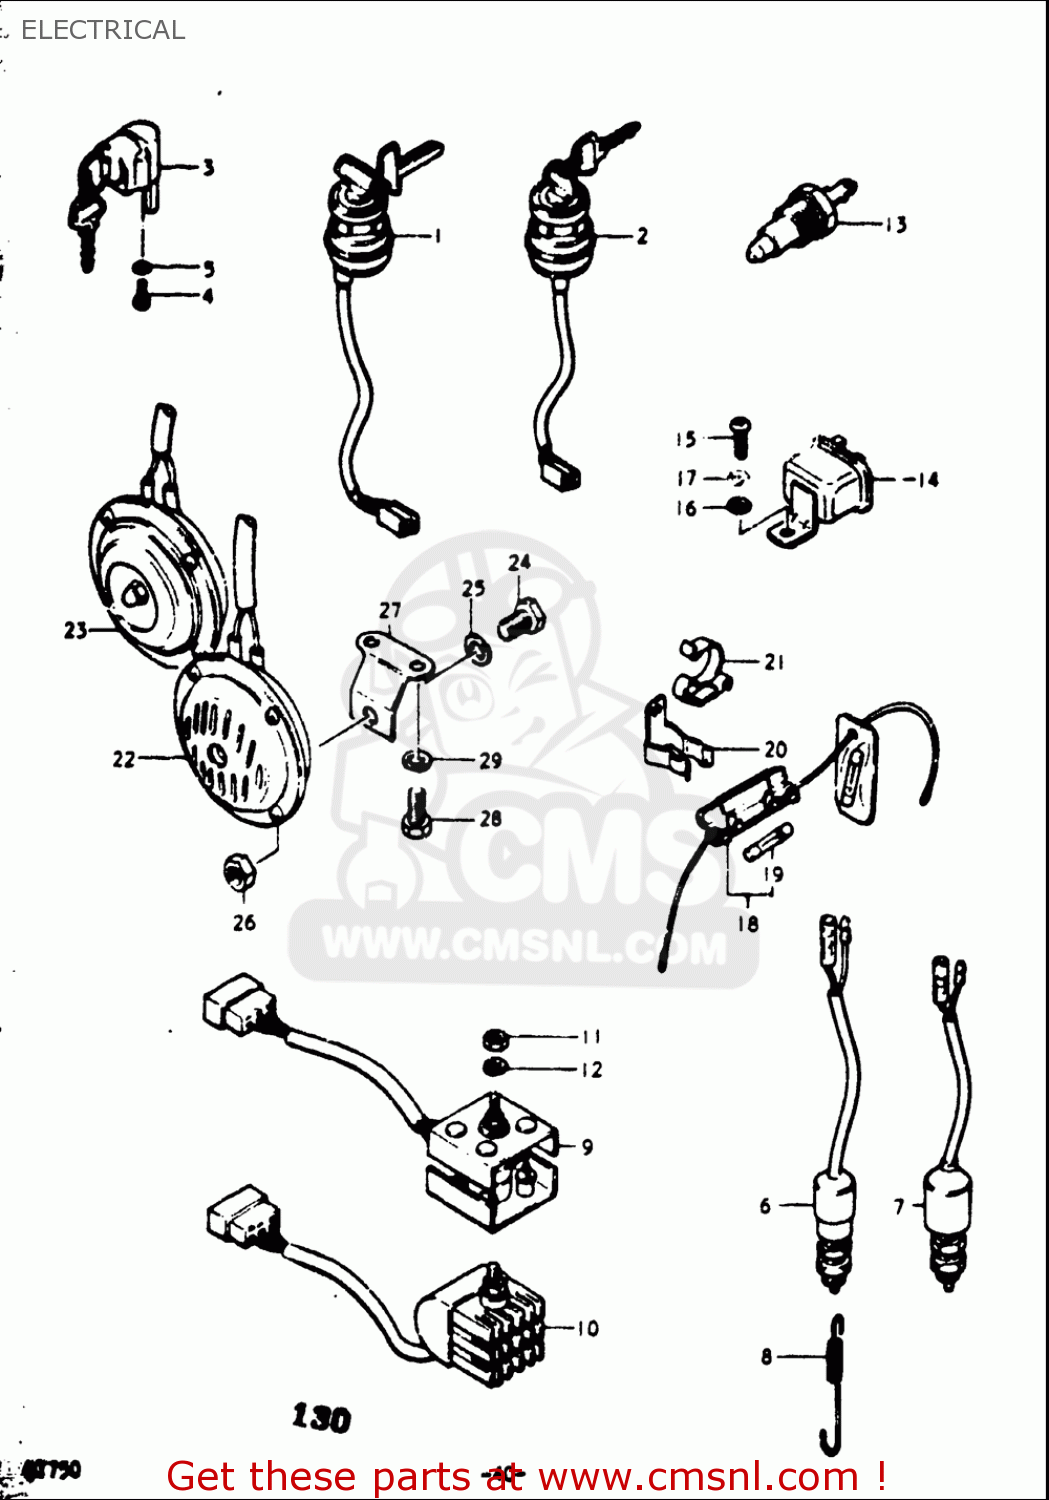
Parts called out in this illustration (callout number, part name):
1	SWITCH ASSY,IGNITION
2	SWITCH ASSY,IGNITION
3	LOCK ASSY,STEERING
4	SCREW
5	WASHER,LOCK
6	SWITCH ASSY,STOP LAMP
8	SPRING
9	RECTIFIER ASSY
10	RECTIFIER ASSY
11	NUT
12	WASHER,LOCK
15	SCREW
16	WASHER
17	WASHER,LOCK
18	CASE ASSY,FUSE
19	FUSE(20A)
23	HORN ASSY
24	BOLT
25	WASHER,LOCK
26	NUT
28	BOLT
29	WASHER,LOCK
